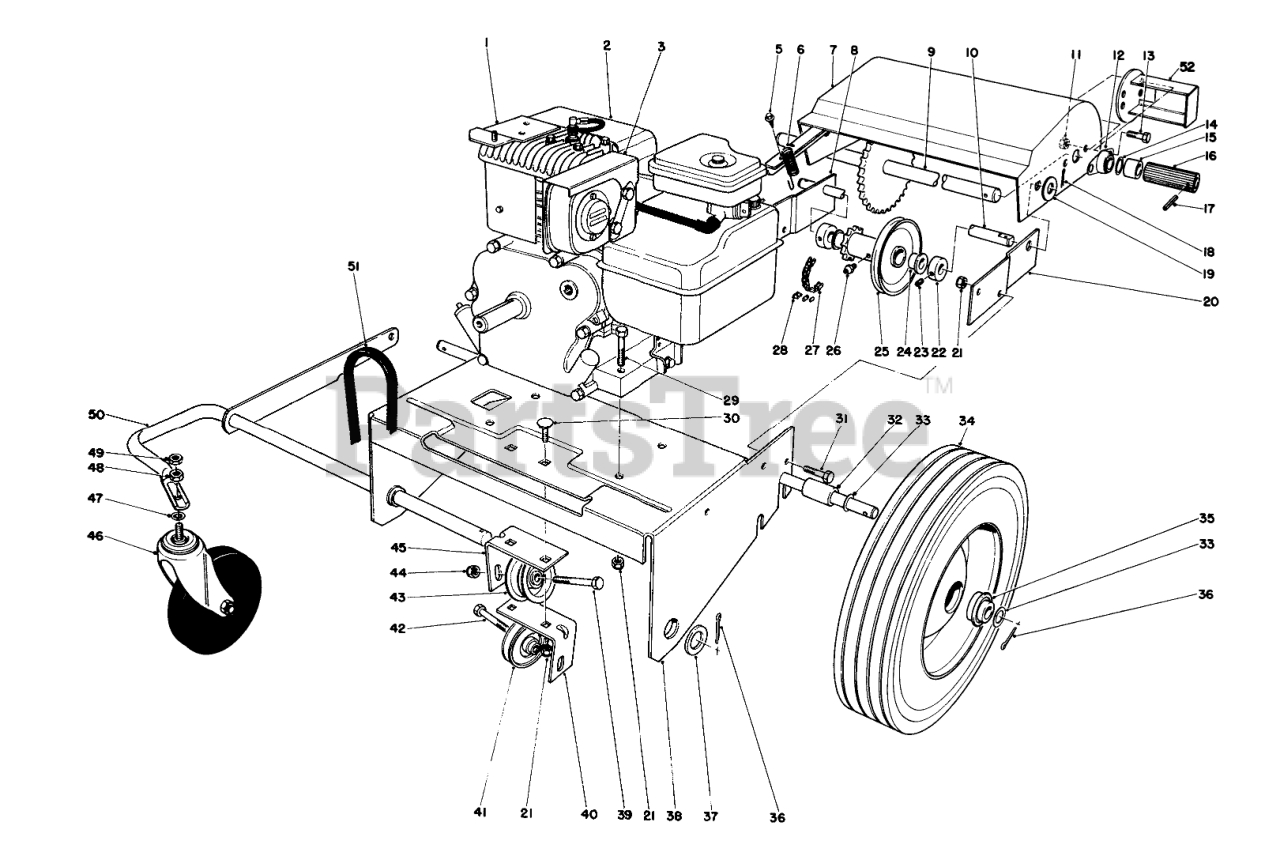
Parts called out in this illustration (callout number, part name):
1	Mounting Bracket
2	Engine
3	HEAT SHIELD
5	SCREW-HH
6	SPRING-TRACTION
7	GUARD WA
8	Mounting Bracket
9	SHAFT-WHEEL, FRICTION
10	SHAFT-IDLER
11	NUT-LOCK, NI
12	BEARING-MOUNT, FLANGE
13	SCREW-HH
14	WASHER
15	SPACER
16	WHEEL-FRICTION
17	PIN-ROLL, SLOTTED
18	PIN-COTTER
19	WASHER-FLAT
20	Mounting Bracket
21	NUT-LOCK, CONE
22	Set Screw Collar (Incl. Ref. #23)
23	SCREW-SET, HSH
24	BUSHING-FLANGE
25	Idler Assembly (Incl. Ref. #24 & 26)
26	FITTING-GREASE
27	Traction Chain (Incl . Ref . #28)
28	LINK-CONNECTING, NO. 35
29	SCREW-HH
30	SCREW-CARR
31	SCREW-HH
32	SPACER-AXLE
33	WASHER
34	Wheel (Incl. Ref. #35)
35	BEARING
36	PIN-COTTER
37	WASHER-FLAT
38	Engine Plate
39	SCREW-HH
40	Bracket-Idler Mount L.H.
41	PULLEY-IDLER
42	SCREW-HH
43	PULLEY-IDLER
44	NUT-LOCK, CONE
45	Bracket-Idler Mount R.H.
46	CASTER
47	WASHER-LOCK/INT
48	NUT-HH
49	1/2-13 CONELOCK NUT
50	Front Wheel Support
51	BELT-V
52	Guard
